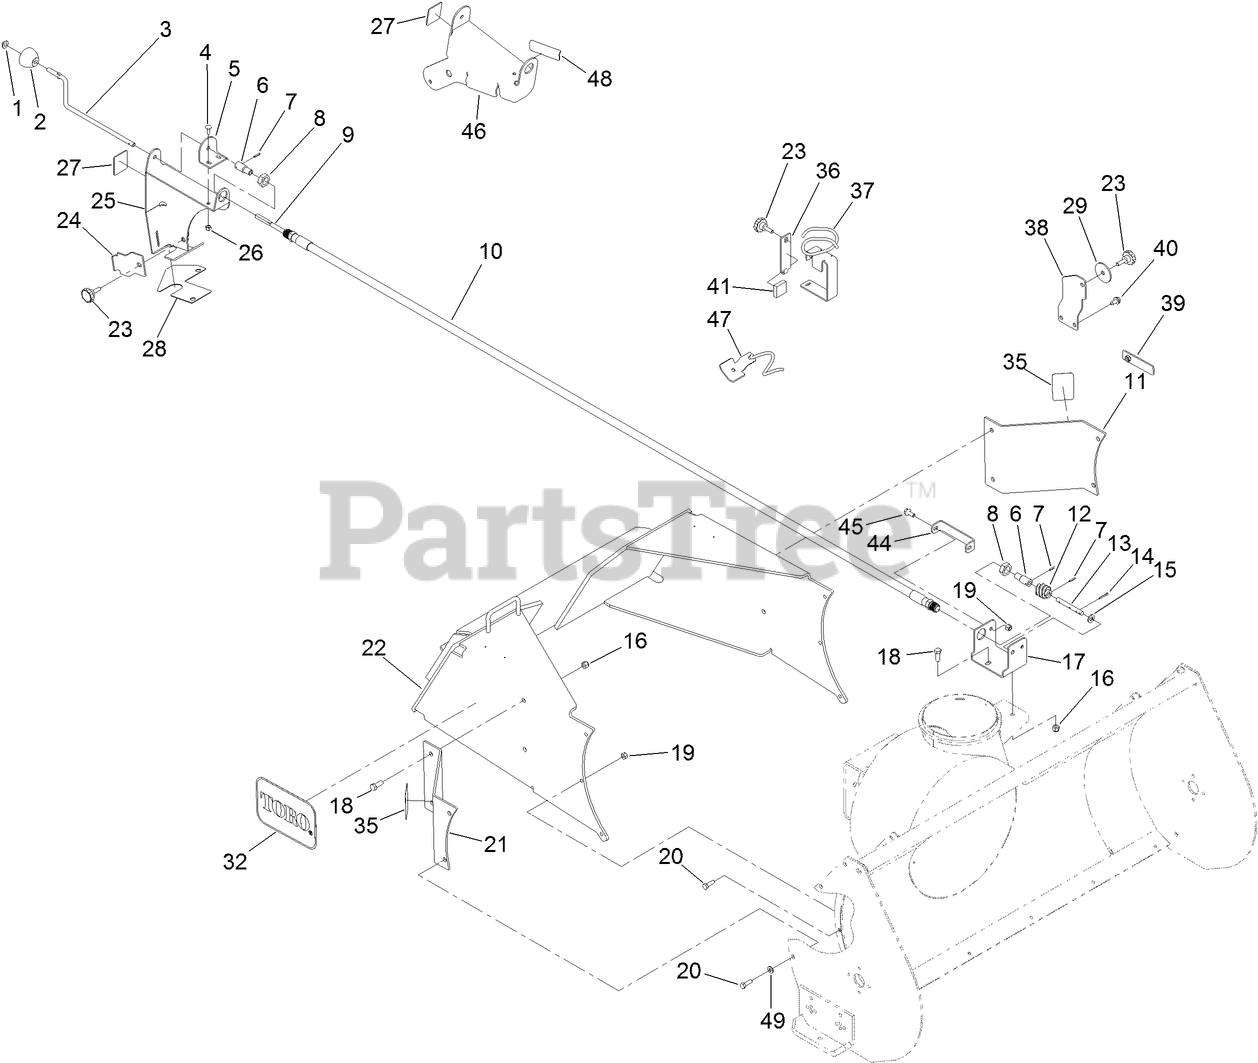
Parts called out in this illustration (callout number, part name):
1	NUT-PUSH
2	KNOB-CHUTE
3	ROD-CONTROL, CHUTE
4	BOLT-CARR
5	BRACKET-ROD, SUPPORT
6	COUPLER
7	PIN-SPRING
8	LOCKNUT
9	SHAFT-FLEXIBLE
10	HOSE ASM
11	PLATE-EXTENSION, LH
12	GEAR-WORM, CHUTE
13	SHAFT-GEAR, WORM
14	PIN-COTTER
15	WASHER-FLAT
16	NUT-LOCK, NI
17	BRACKET-WORM GEAR
18	SCREW-HH
19	NUT-LOCK, NI
20	SCREW-HH
21	PLATE-EXTENSION, RH
22	MOUNT-SNOWTHROWER
23	KNOB-CONTROL, CHUTE
24	BRACKET-CLAMP
25	BRACKET-CONTROL, CHUTE
26	NUT-LOCK, NI
27	DECAL-CHUTE DIRECTION
28	FOAM-CHUTE, CONTROL
29	WASHER-FLAT
32	DECAL
35	REFLECTOR
36	BRACKET-RETAINER
37	RETAINER-HOSE
38	BRACKET,CLAMP
39	PLATE-RETAINER
40	SCREW-HWHTF
41	PAD-RETAINER, BRACKET
44	BRACKET-STIFFENER
45	SCREW-HHF
46	BRACKET-CHUTE CRANK
47	GUIDE ASM
48	FOAM-CHUTE CONTROL
49	WASHER-PLAIN
